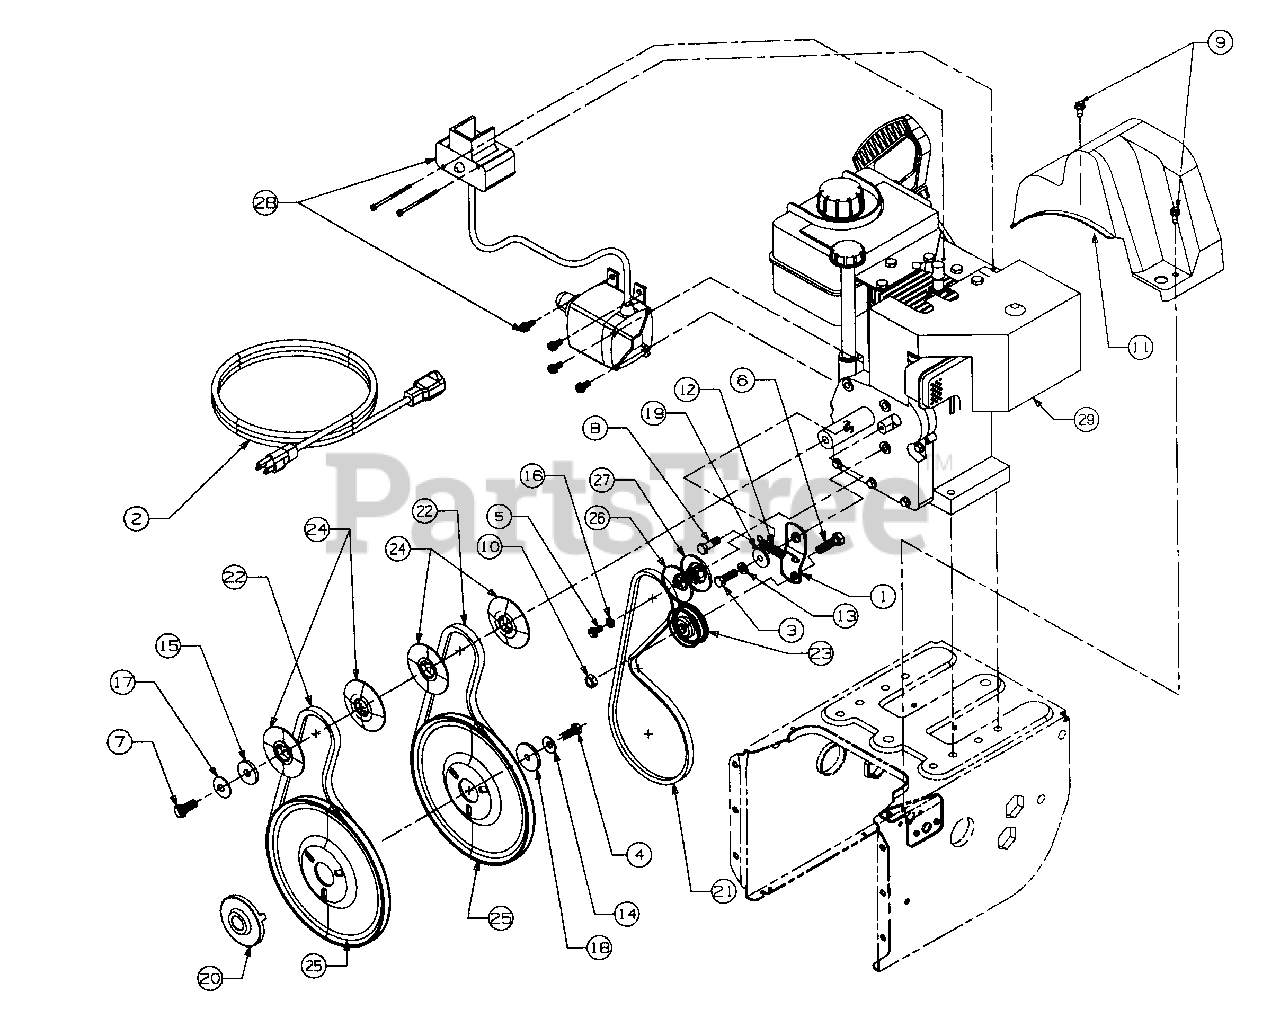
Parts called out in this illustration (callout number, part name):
3	Screw-Hex
4	Screw-Hex
5	Screw-Hex
6	Screw-Hex
7	Screw-Hex
8	Screw-Hex
9	Screw-Hex
10	Nut-Hex
11	Cover-Belt
12	Spring
13	Washer-Lock
14	Washer-Bell
15	Washer-Flat
16	Washer-Lock
17	Washer-Bell
18	Washer-Flat
19	Spacer
20	Adapter-Pulley
21	V-Belt
22	V-Belt
23	Idler-Flat
24	Pulley Half
25	Pulley-Auger
26	Pulley Half
27	Pulley Half
28	Electric Start Kit
